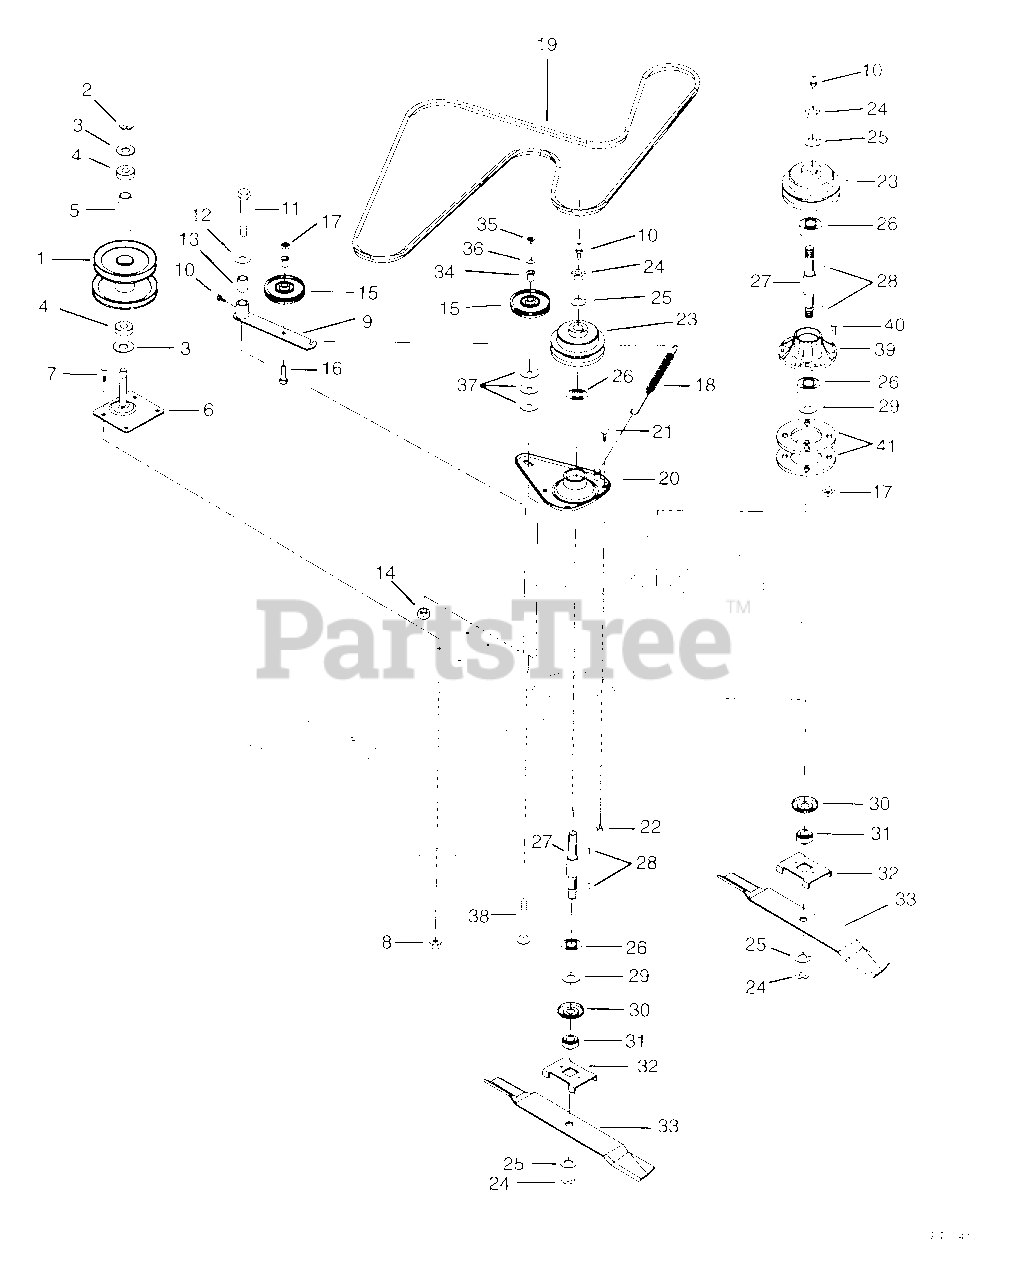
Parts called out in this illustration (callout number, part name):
1	JACKSHAFT - 48" DECK
2	NUT-LK-NYL.625-18 PL
3	WSHR-FL-STL .640X1.005X.062 PL
4	BRG-BALL .625X1.375X.44
5	SPACER .640X.880X2.545
6	PLATE - MOUNT
7	BLT-RDHDSQNK .312-18X.62SHTPL
8	NUT-FLG. .312-18 PL
9	ARM - IDLER
10	FTG-LUBE .25-28X.256 YWZC
11	BLT-HEX .50-13X2.75 PL GR5
12	WSHR-FL-STL .505X.880X.072 PL
13	SPACER, PIVOT .500X.750X1.805
14	NUT-LK-CTR .50-13
15	IDLER, PLASTIC, 4.00 X .50 ID
16	BLT-HEX .38-16X1.25 PL GR5
17	NUT-LK-JAM-CTR .375-16 PL
18	SG-TENS .075X.75X2.25 WLD20.7
19	V-BELT, 4L-WRAPPED
20	HOUSING, SPINDLE
21	BLT-RDHDSQNK .38-16X.62 GR5 PL
22	NUT-LK-CTR .375-16 GR A PL
24	NUT-JAM .75-10 PL
25	WSHR-LK .750X.188 MED PL
26	BRG-BALL .750X1.781X.61
27	SPINDLE SHAFT W/ZERK
28	KEY-WDRF .188X.625X.25 SAE 61
29	WSHR-FL-STL .754X1.000X.032
30	BEARING SLINGER
31	RETAINER HUB
32	BLADE TRAY 48
34	SPACER -FLANGED .390X.500X.781
35	NUT-LK-NYL .375-16 PL
36	WSHR-FL-STL .38X.875X.083 PL
37	WSHR-HDND-THR .390X1.50X.125PL
38	BLT-RDHDSQNK .38-16X2.00
39	SPINDLE HOUSING
40	BLT-RDHDSQNK .375-16X.75 PL
41	SPACER, SPINDLE
